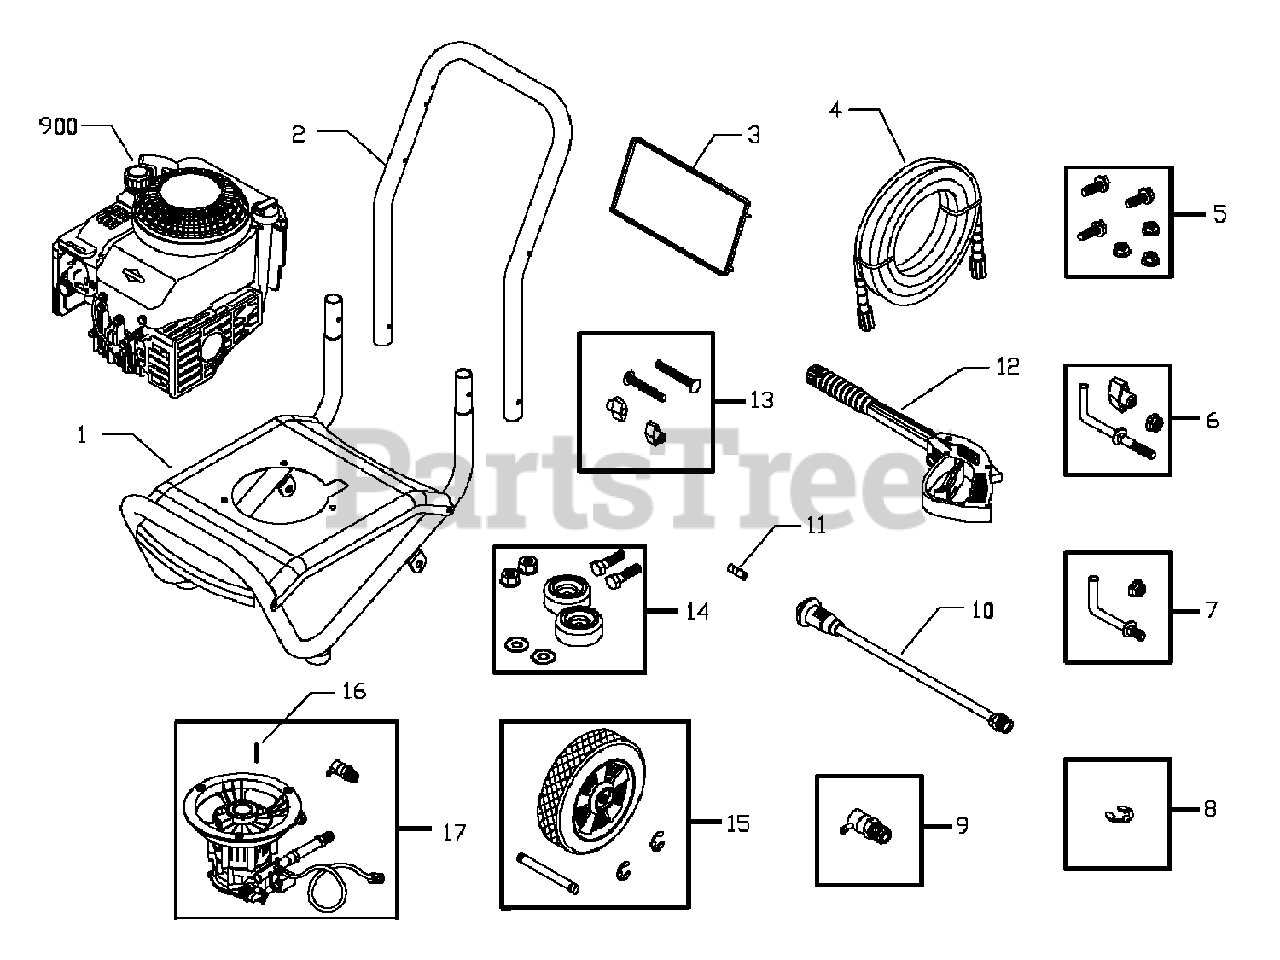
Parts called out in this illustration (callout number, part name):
1	ASSY, Base
3	ASSY, Billboard with Decal
4	HOSE
5	KIT, Pump Mounting Hardware
6	KIT, Hook, Handle
7	KIT, Hook, Base
8	KIT, E-Ring
9	VALVE, Thermal Relief
10	WAND, Adjustable Nozzle
11	ORIFICE
12	GUN
13	KIT, Handle Connector
14	KIT, Vibration Mount
15	KIT, Wheel
17	ASSY, Pump (see next page)
900	§ ENGINE
